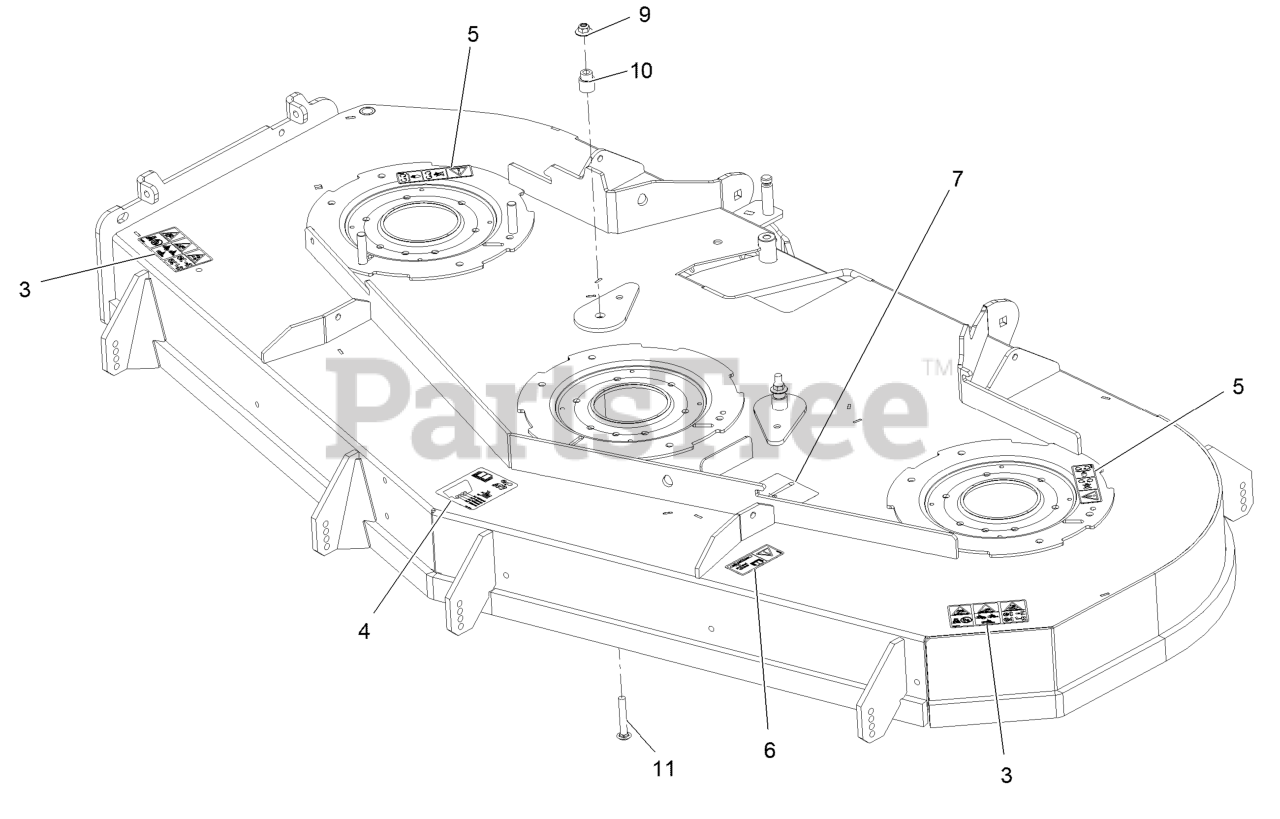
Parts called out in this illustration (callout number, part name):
3	DECAL-DANGER THROWN OBJECTS
4	DECAL-ROLLER, ANTI-SCALP
5	DECAL-COVER, MISSING
6	DECAL-BOLT TORQUE
7	DECAL-BELT ROUTING
9	Nut-Nyloc 3/8-16 Flg
10	BUSHING-IDLER
11	SCREW-CARR
